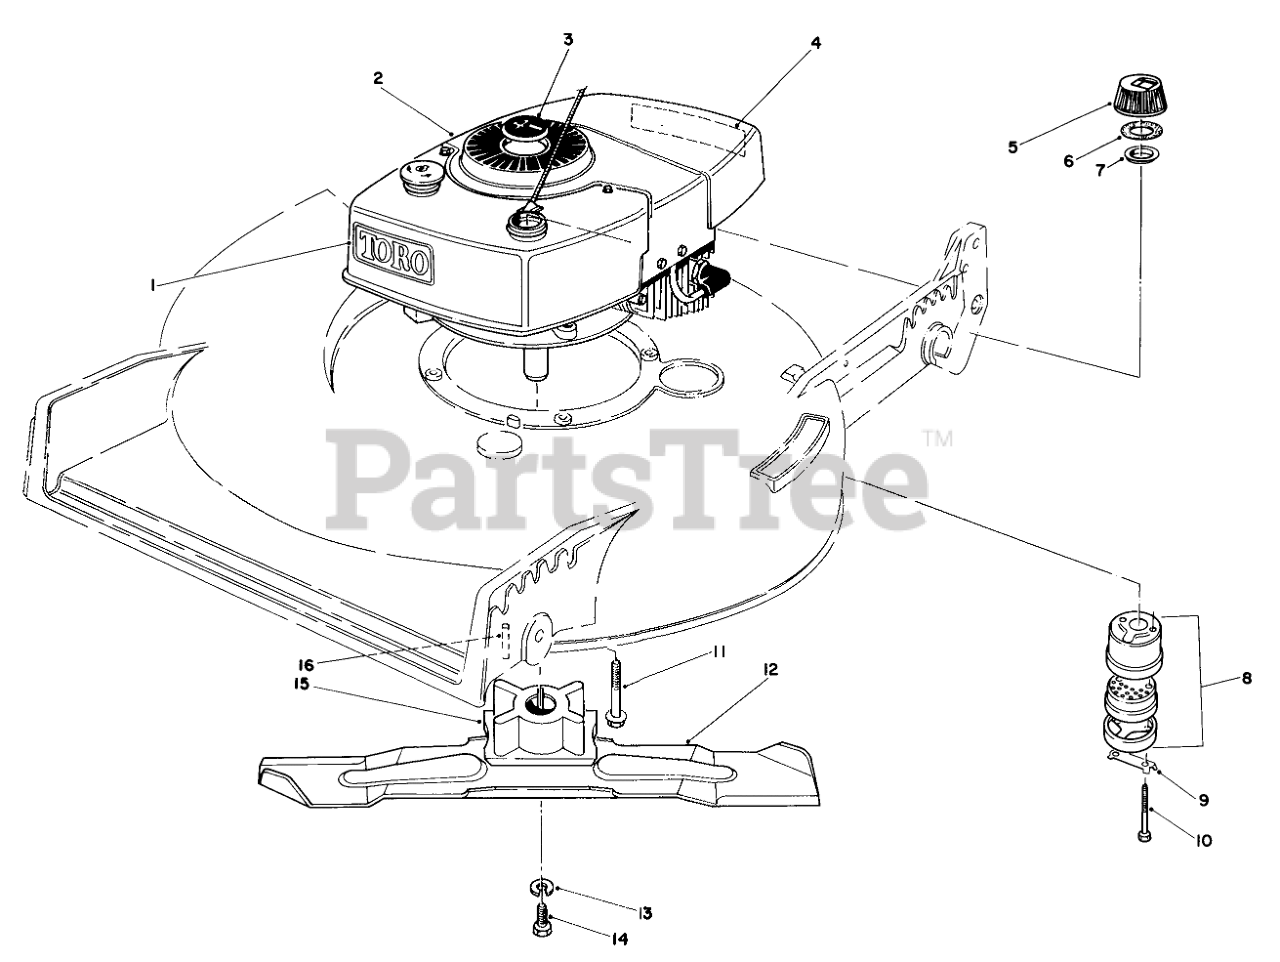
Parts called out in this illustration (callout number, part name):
1	Decal Tow
2	Engine
3	PLUG BUTTON
4	Decal-Maintenance
5	Fuel Cap Assembly (Incl. Ref. #6 & 7)
6	GASKET
7	GAS CAP BAFFLE
8	Muffler Assembly (Incl. Ref. #9 & 10)
9	CLIP - LOCKING
10	SCREW-HH
11	3/8-16 X 2 CAPSCREW
12	BLADE-21in
13	WASHER-LOCK
14	SCREW-BLADE
15	BLADE RETAINER(DEEP)
16	KEY-SQUARE
